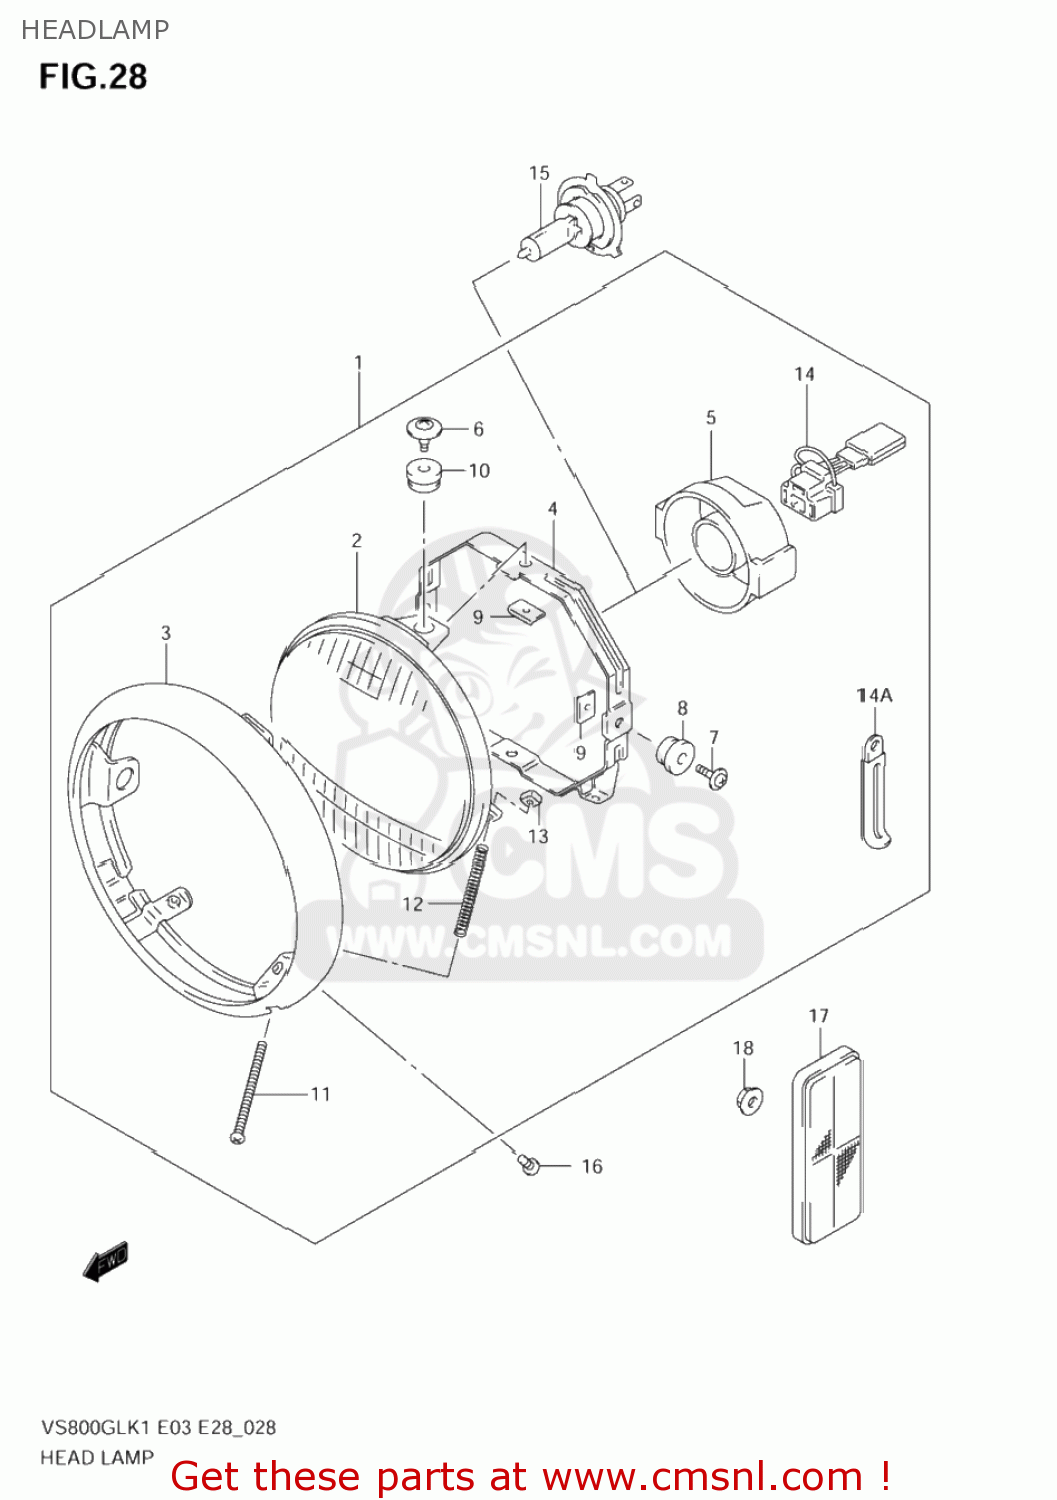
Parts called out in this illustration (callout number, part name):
1	HEADLAMP ASSY
2	UNIT,LAMP
3	RIM
4	RING,MOUNTING
5	COVER
6	SCREW
7	SCREW,MOUNTING
8	CUSHION
9	NUT
10	CUSHION
11	SCREW,ADJUSTING(4X50)
12	SPRING
13	NUT,HEADLAMP ADJUST
14	SOCKET
14A	CLAMP(L:65)
15	BULB(12V60/55W,H4)
16	SCREW
17	REFLEX REFLECTOR,FR SIDE
18	NUT
